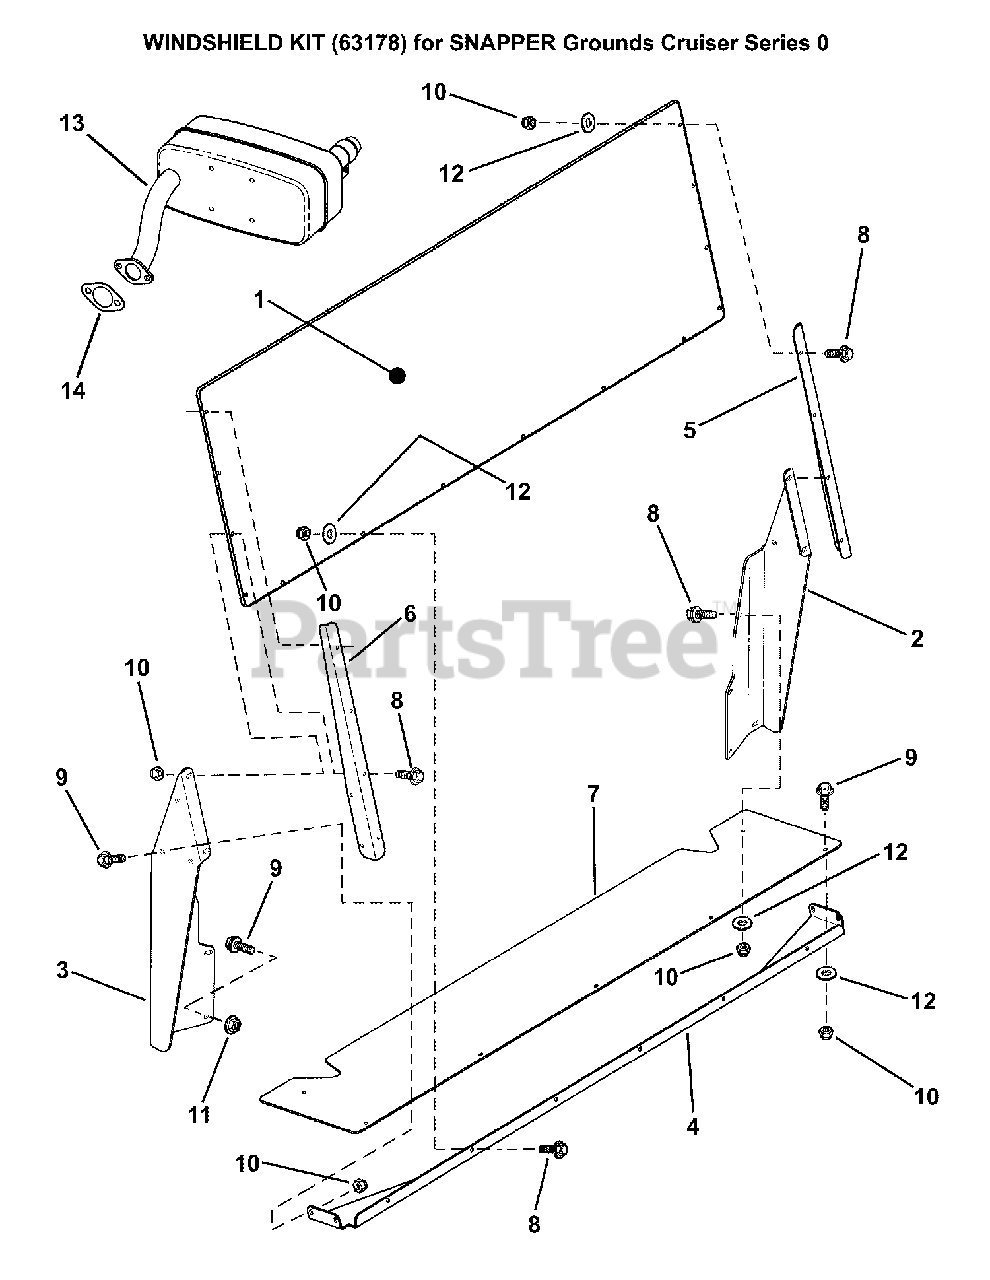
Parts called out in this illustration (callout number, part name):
1	WINDSHIELD, Grounds Cruiser
2	BRACKET, LH Windshield Mount
3	BRACKET, RH Windshield Mount
4	BRACKET, Lower Windshield Frame
5	BRACKET, LH Windshield Frame
6	BRACKET, RH Windshield Frame
7	WIND GUARD, Rubber
8	BOLT, 1/4-20 x 1" Hex Flange Lock
9	BOLT, 1/4-20 x 5/8" Hex Flange Lock, GR5
10	NUT, 1/4-20 Hex Nyloc
11	NUT, 1/4-20 Hex Flange Lock, GR5
12	WASHER, 1/4" Flat
13	MUFFLER, Welded, Utility Vehicle
14	GASKET, Kawasaki Exhaust
